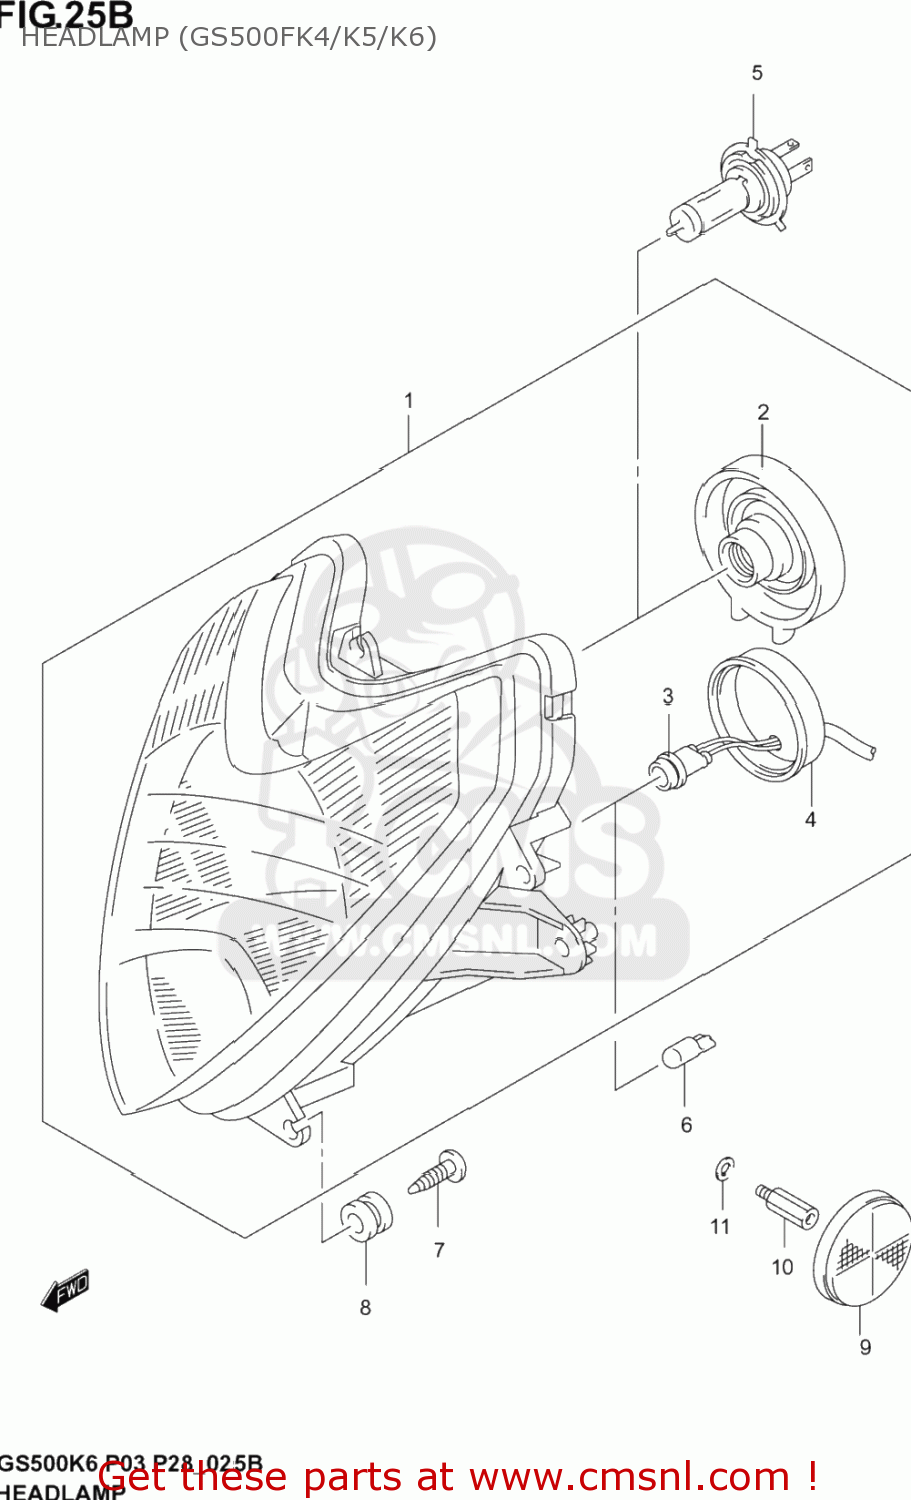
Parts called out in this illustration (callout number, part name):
1	HEADLAMP ASSY
2	COVER, SOCKET
3	COVER
5	BULB(12V60/55W,H4)
6	BULB(12V5W)
7	SCREW(5X15)
8	CUSHION
9	REFLECTOR,REFLEX FR
10	BOLT(5X10)
11	WASHER
